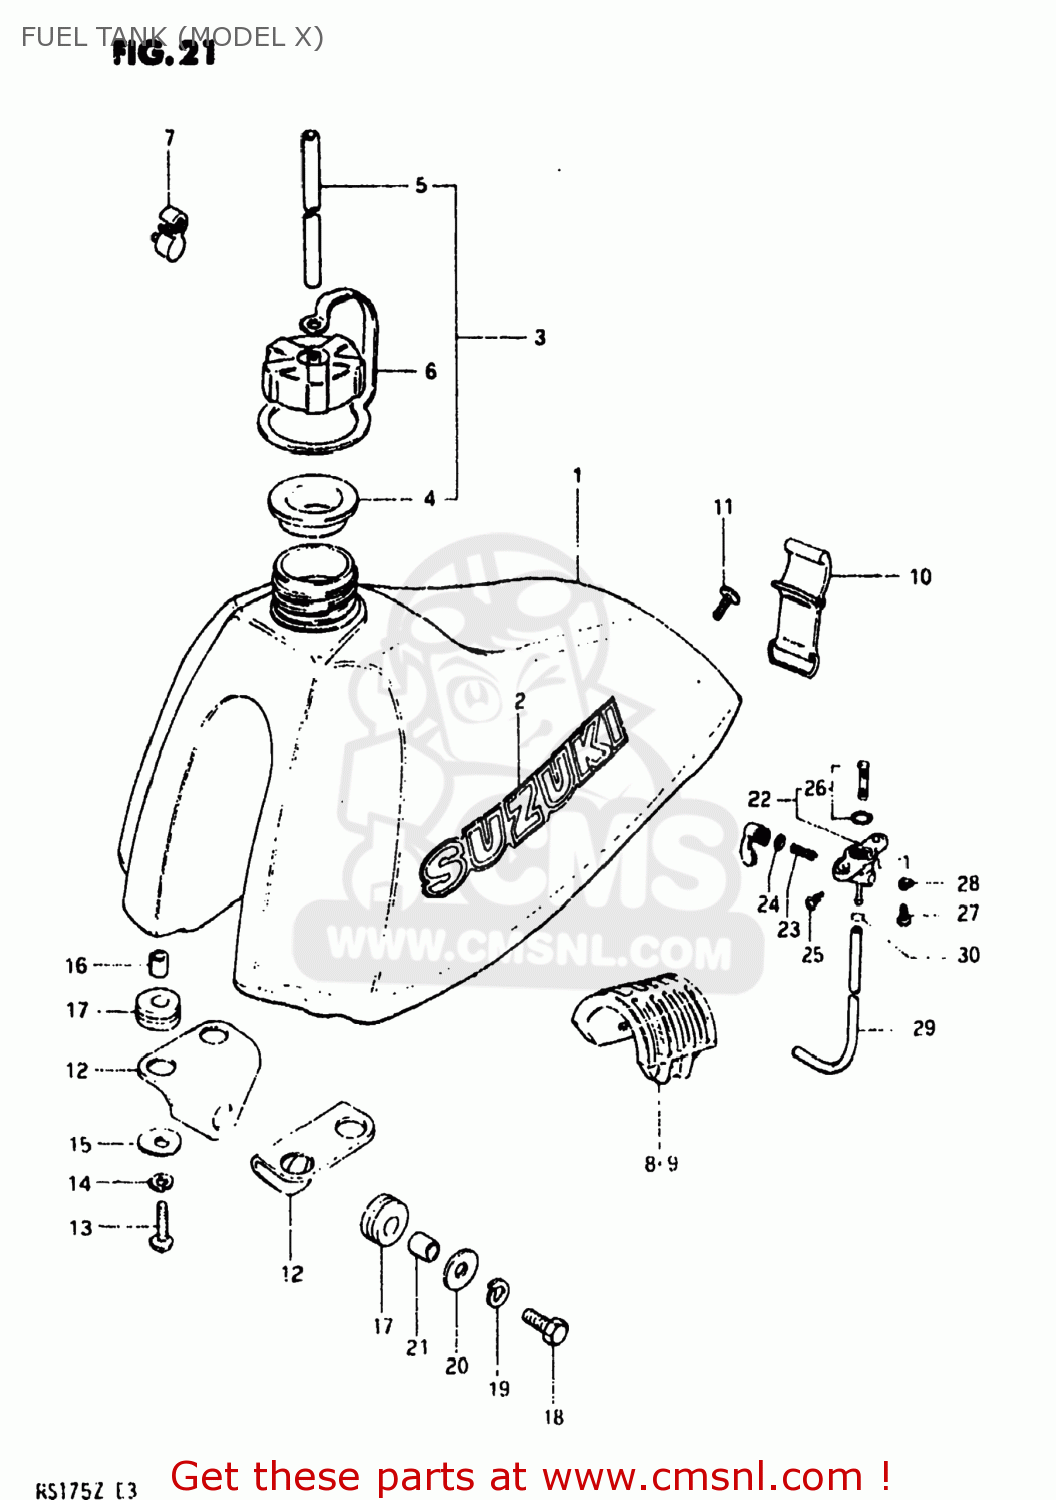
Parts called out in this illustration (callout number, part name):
1	TANK ASSEMBLY,FUEL
2	EMBLEM
3	CAP SET,FUEL TANK
4	GASKET,FUEL TANK CAP (NAS)
5	HOSE
6	BAND,FUEL TANK CAP
7	CLAMP,BREATHER HOSE
8	CUSHION,FUEL TANK
9	CUSHION,FUEL TANK
10	BAND
11	SCREW(6X18)
12	BRACKET,FUEL TANK,LOWER
13	SCREW
14	LOCK WASHER
15	WASHER (6.5X24X1.6)
16	SPACER(6.8X12X11)
17	CUSHION
18	BOLT (8X30)
19	LOCK WASHER
20	WASHER (8.2X24X1.6)
21	SPACER (8.8X12X11)
22	COCK ASSEMBLY,FUEL
23	SPRING,FUEL COCK VALUE
24	O RING,LEVER
25	SCREW
26	FILTER SET FUEL
27	SCREW
28	LOCK WASHER
29	HOSE
30	CLAMP
